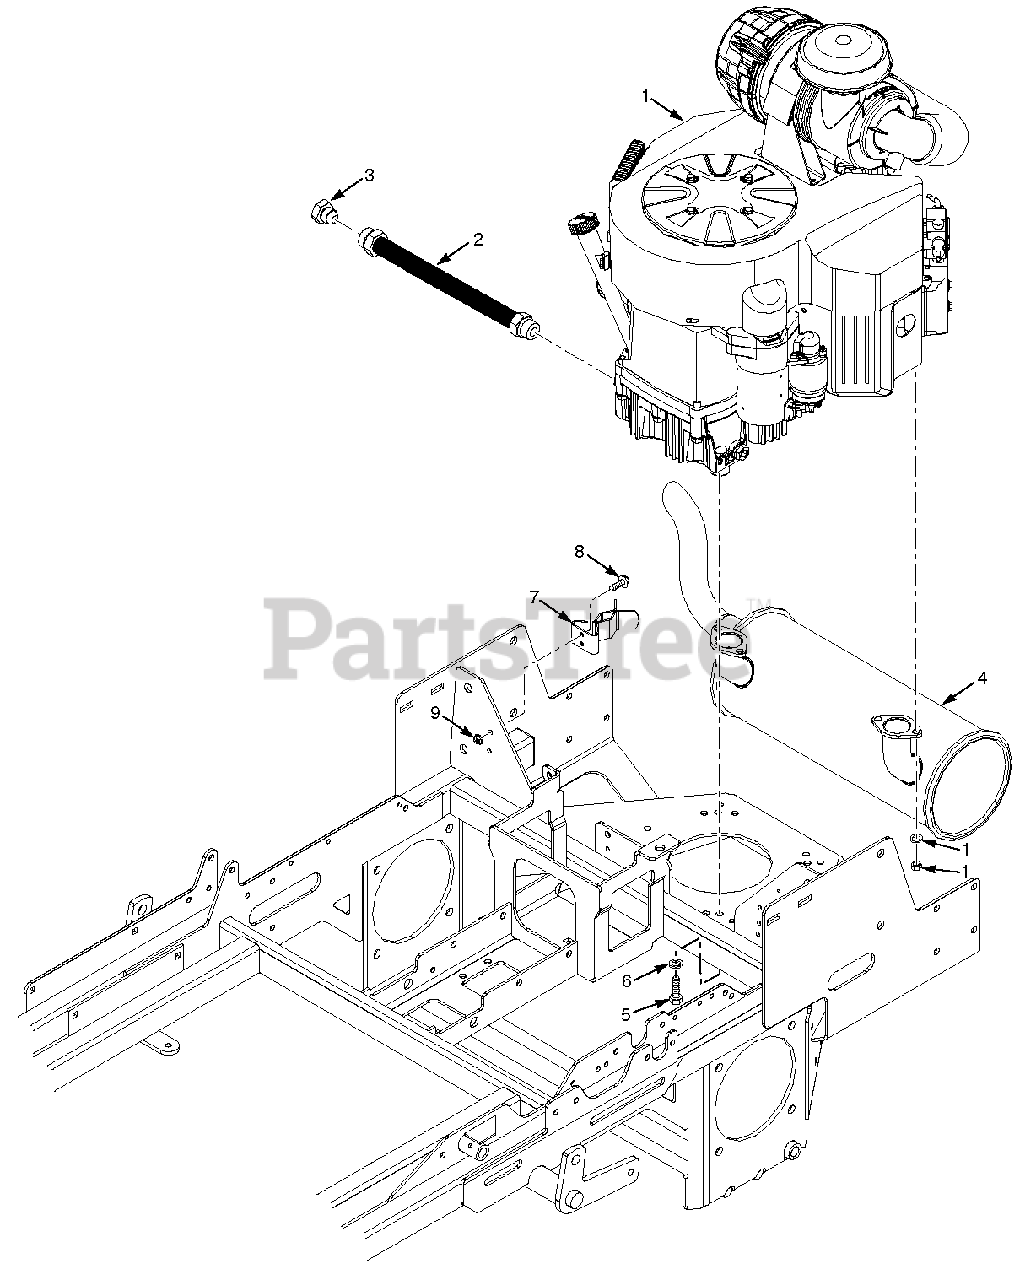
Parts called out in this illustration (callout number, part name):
1	Engine, 31hp
1	Engine, 32hp
1	Engine, 34hp
2	Hose, Oil Drain
2	Hose, OIl Drain
4	Muffler
4	Pipe, Muffler Extention
5	Bolt, Hex Head 3/8-16 x 1-1/4"
5	Bolt, Hex Head 5/16-18 x 1-1/2"
5	Nut, Serrated Flange 5/16-18
6	Lockwasher, 3/8" Spring
7	Spring Clip
8	Screw, #8-32 x 1/2"
9	Nut, Elastic Stop #8-32
